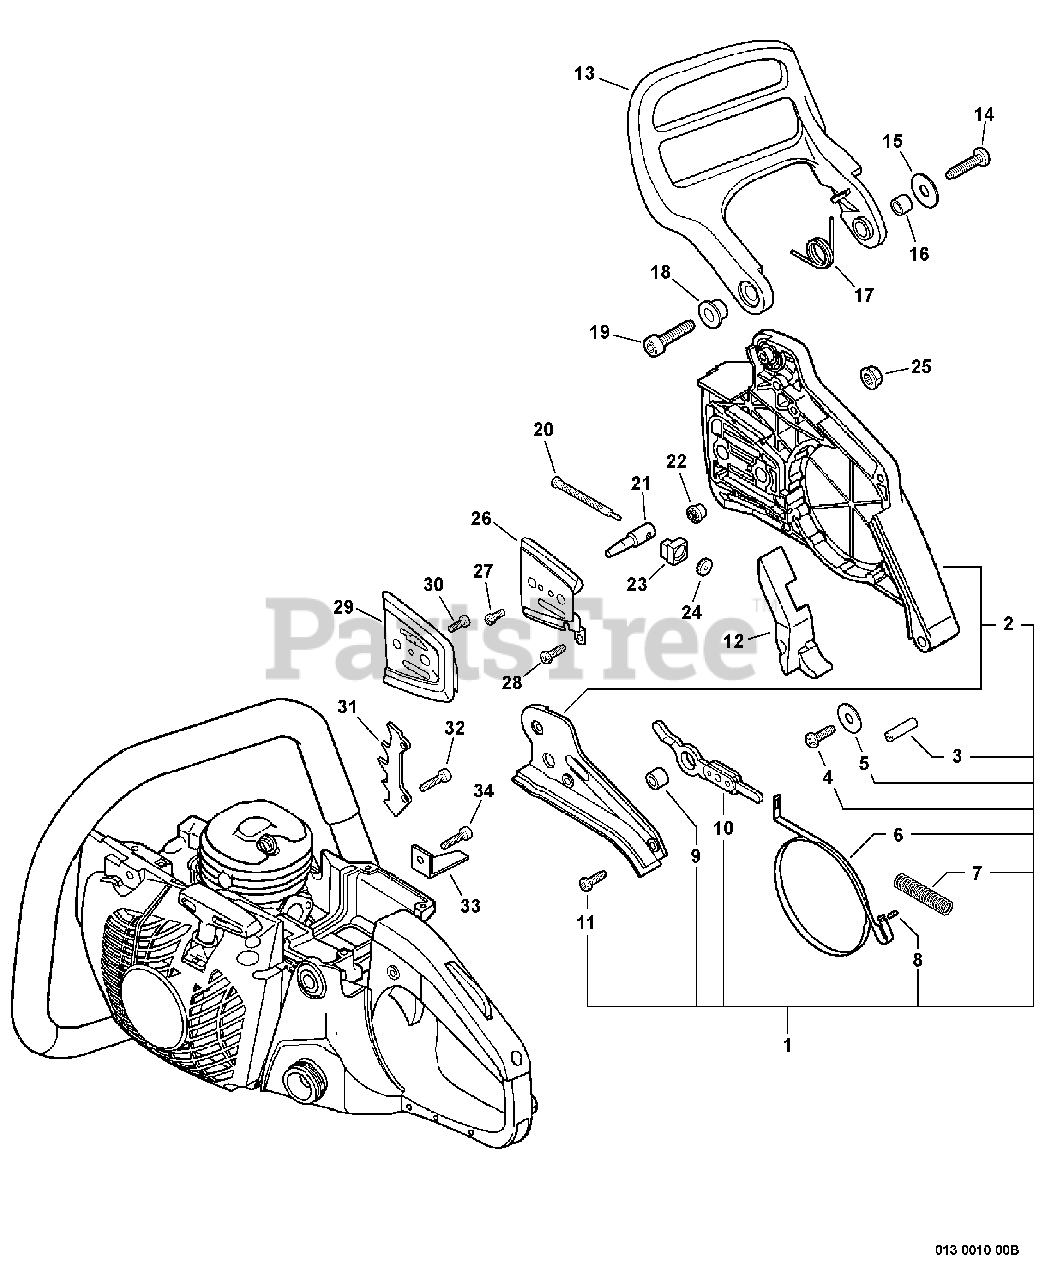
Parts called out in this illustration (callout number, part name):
1	BRAKE ASSY, CHAIN
2	SPROCKET GUARD KIT
3	PIN, SPRING 6×25
4	SCREW 4×16
6	BAND, BRAKE
7	SPRING, COMPRESSION
8	PIN 3×12
9	SPACER 8×12×9
10	CONNECTOR, BRAKE
11	SCREW 4×12
12	CUSHION
13	LEVER, BRAKE
14	BOLT 4×14
15	WASHER 4.2×16.5×1
16	SPACER 8×12×9
17	SPRING, TORSION
18	COLLAR 10
19	BOLT 5×30
20	SCREW, CHAIN TENSION
21	TENSIONER, CHAIN
22	GEAR, BEVEL
23	COLLAR 8
24	GEAR, BEVEL
25	NUT, FLANGE M8×1.25
26	PLATE, GUIDE - OUTER
27	SCREW 3×6
28	SCREW 4×12
29	PLATE, GUIDE - INNER
30	SCREW 4×6
31	SPIKE, BUMPER
32	BOLT 5×12
33	CHAIN CATCHER
34	BOLT 5×14
